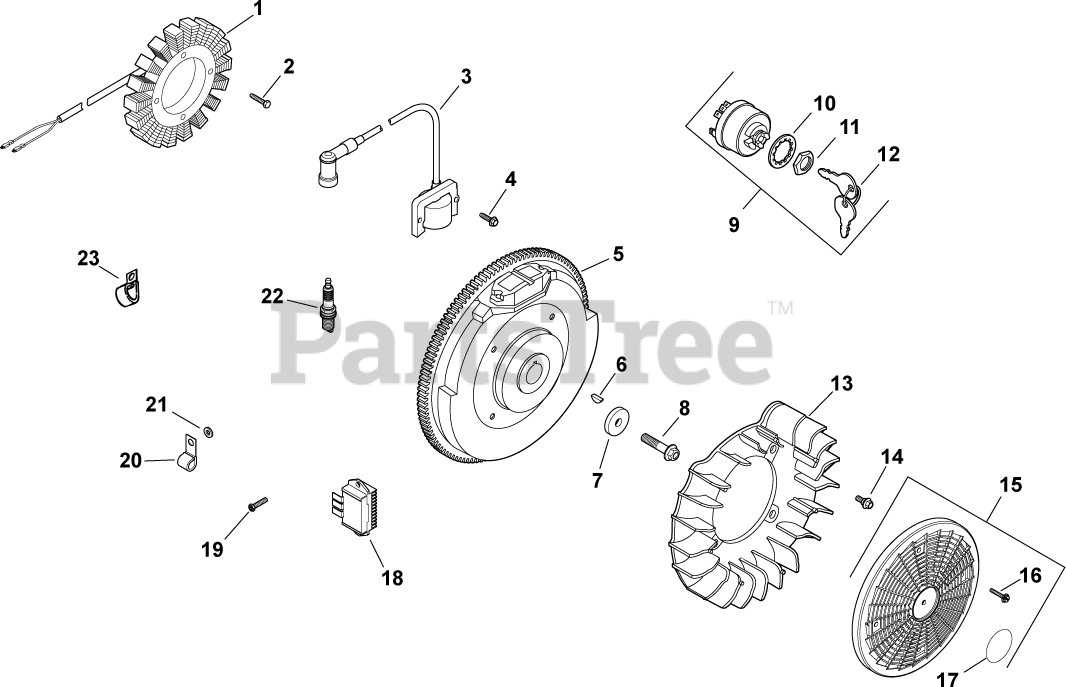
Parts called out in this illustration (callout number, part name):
1	KIT, 15 / 20 AMP STATOR
2	SCREW, M5X0.8X25 - (#25086402S)
3	KIT, MODULE IGNTN (CDI FIXED)
4	SCREW, FLG THD FRM M5X.8X20-(#25086399S)
5	FLYWHEEL, PAINTED-USE 24 025 55-S
6	KEY, 3/16" X 5/8"
7	WASHER, FLAT 13/32"
8	SCREW, FLG M10X1.5X45 - (#25086361S)
9	SWITCH ASSY, KEY (KM)-USE 25 099 32-S
10	WASHER, INTERNAL TOOTH
11	NUT, KEY SWITCH
12	KEY, SET -USE 48 340 01-S
13	FAN USE 24 755 253-S
14	BOLT, SHOULDER
15	KIT, GRASS SCREEN
16	SCREW, FLG SEMS M4X.7X25
17	DECAL, GRASS SCREEN USE 24 113 499-S
18	REG/RECT-15 AMP (KM)-USE 41 403 10-S
19	SCREW, PHL HD #11-16X7/8"
20	CLIP, CABLE
21	WASHER, FLAT 1/4" (O.D. 1/2")
22	PLUG, SPARK (PRO SERIES)
23	CLIP, TUBE & WIRING (KM)
